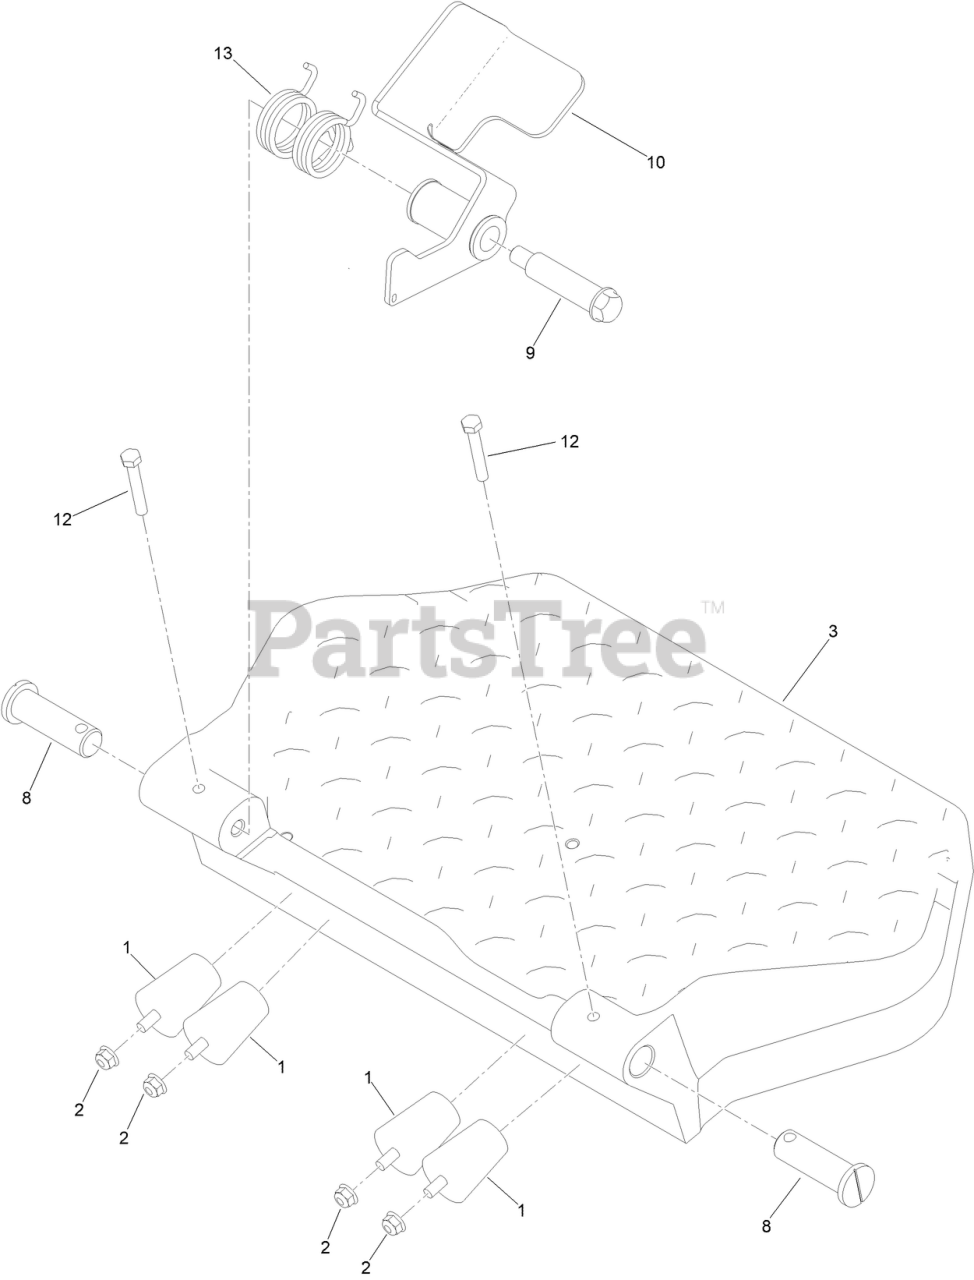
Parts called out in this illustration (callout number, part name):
1	BUMPER
2	NUT-HF, NI
3	OPERATOR PLATFORM [BLK-TXT]
8	PIN-PLATFORM
9	BOLT-SHOULDER
10	PEDAL ASM [BLK-TXT]
12	SCREW-HH
13	SPRING-TORSION, TWIN COILS
